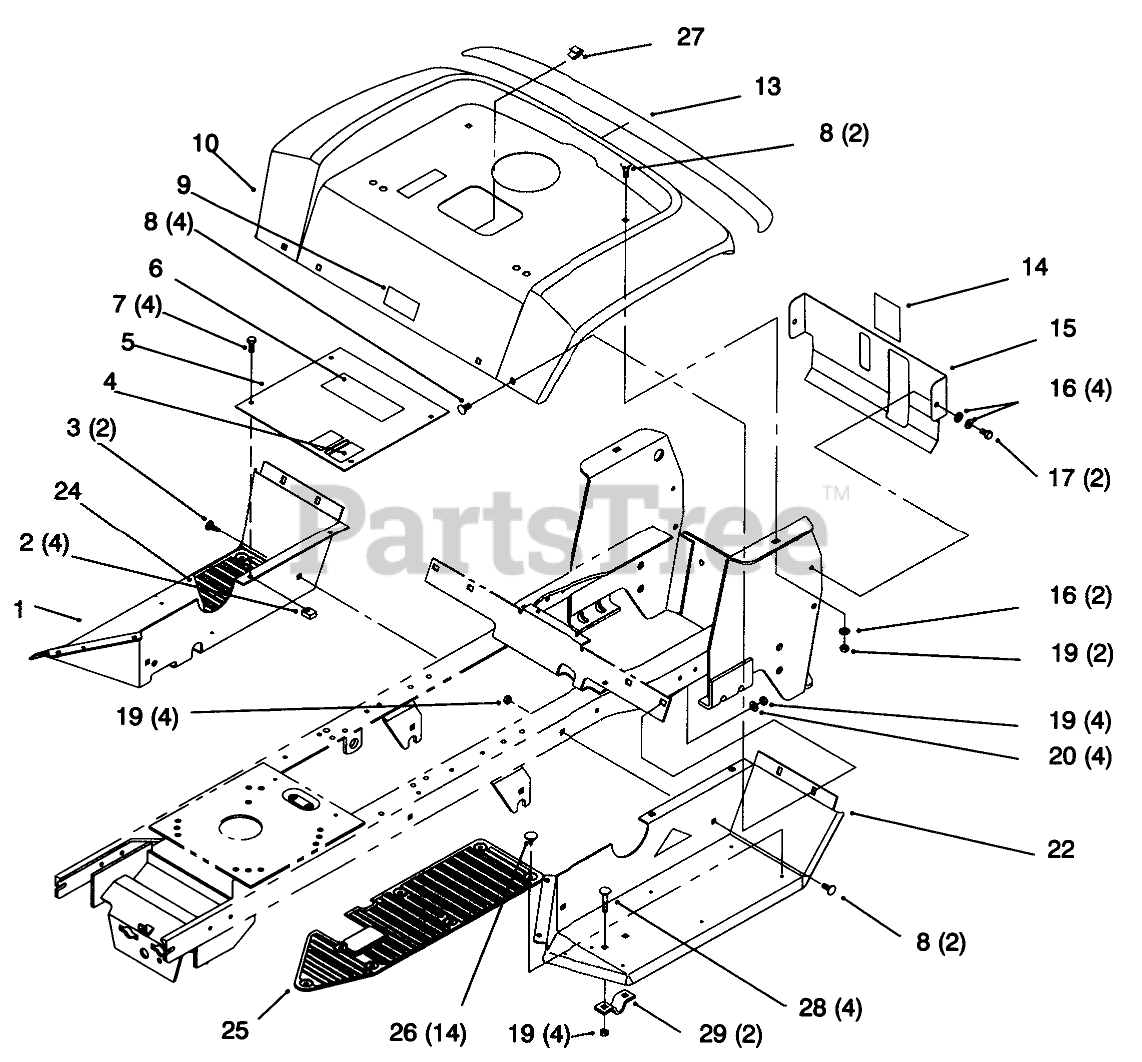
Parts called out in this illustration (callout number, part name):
1	Footrest-RH (Only On: 72042, 72062)
1	Footrest-RH (Only On: 72043, 72063, 72103)
2	Nut-Retainer
3	SCREW-CARR
4	Decal-HOC (Only On: 72042, 72043)
4	Decal-HOC (Only On: 72062, 72063, 72103)
5	PLT - FTREST W/DECAL
6	DECAL-DANGER
7	SCREW-HH
8	BOLT-CARR
9	Decal-USA (Only On: 72042, 72043)
13	DECAL - REAR FENDER
14	DECAL-LEVEL, FUEL
15	COVER-REAR
16	WASHER-PLAIN
17	SCREW
19	NUT-LOCK, NI
20	WASHER-FLAT
22	Footrest-LH (Only On: 72042, 72062)
22	Footrest-LH (Only On: 72043, 72063, 72103)
24	Mat-Foot RH (Only On: 72043, 72063, 72103)
24	Mat-Foot RH (Only On: 72042, 72062)
25	Mat-Foot LH (Only On: 72043, 72063, 72103)
25	Mat-Foot LH (Only On: 72042, 72062)
26	FASTENER-PANEL
27	CLIP-RETAINER, WIRE
28	SCREW-CARR
29	CLAMP
